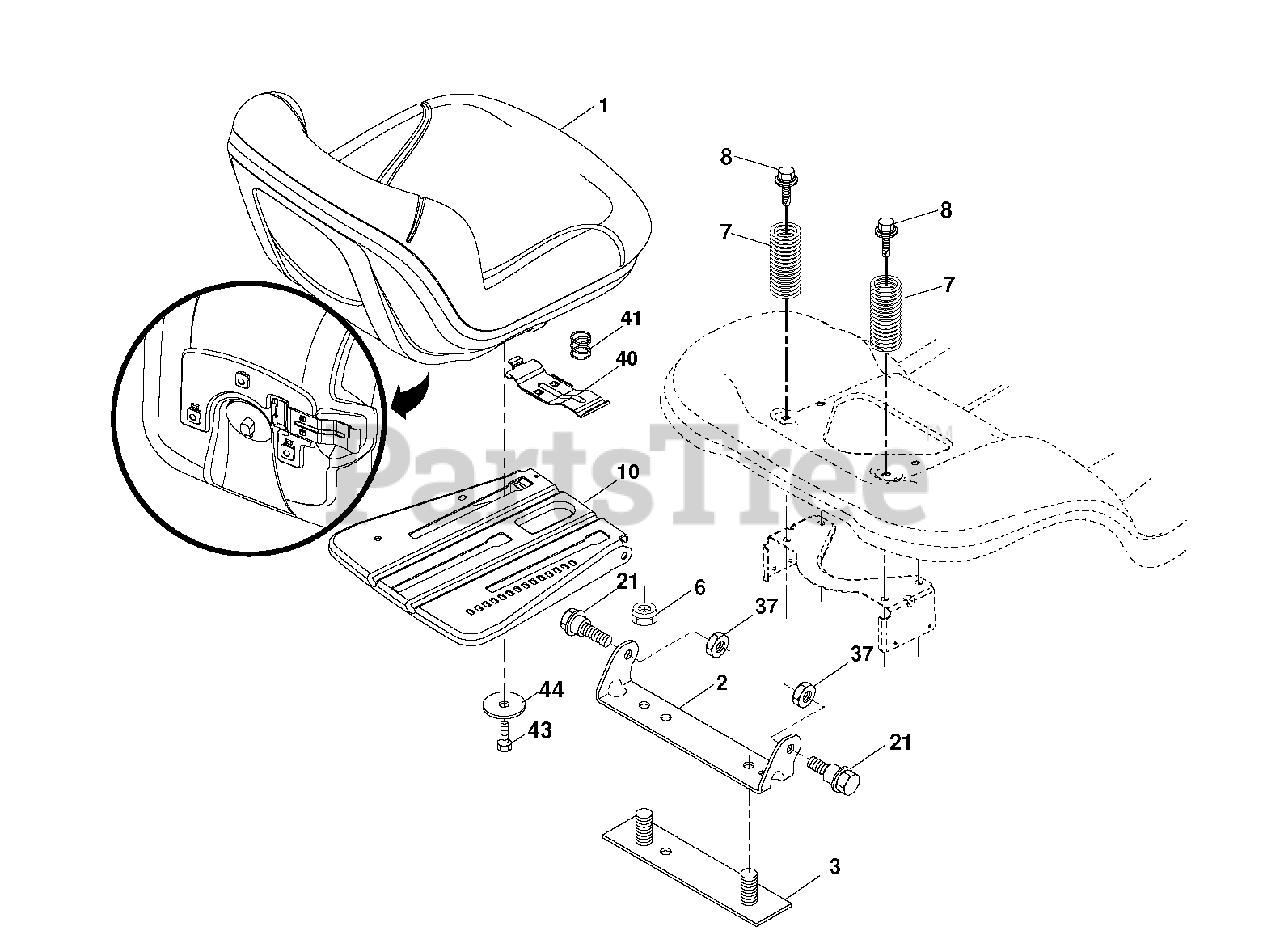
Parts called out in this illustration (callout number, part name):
1	SEAT.TG150.BLK.NLOGO.
2	BRKT.PIVOT.FENDER
6	NUT
7	SPRING COMPRESSION
8	BOLT, 5/16-18 X 1 3/4
10	PAN.ASM.SEAT.3PT
21	BOLT.SHOULDER.5/16-18
37	NUT.71038.31-18.HEX.NYLOCK
40	HANDLE.SLIDE.SEAT.TEX.BLACK
41	SPRING.LATCH.SEAT.TEX
44	WASHER 13/32 X 2-3/8 X 12GA
